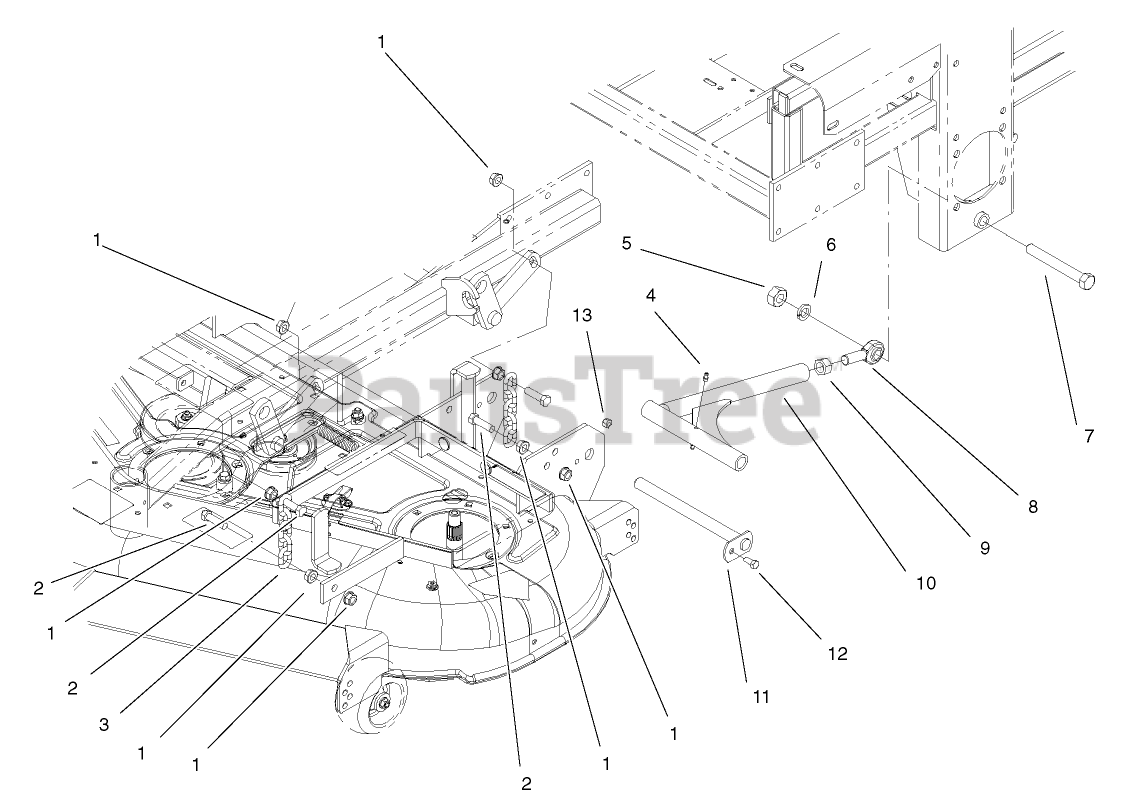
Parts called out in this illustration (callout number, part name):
1	NUT-HF
2	SCREW-CAP, HH
3	CHAIN-LIFT, DECK
4	FITTING-GREASE
5	NUT-HEX
6	WASHER-LOCK
7	SCREW-HH
8	BALLJOINT-SPHERICAL
9	NUT-HEX
10	STRUT
11	PIN-STRUT
12	SCREW-HH
13	NUT-LOCK, NI
